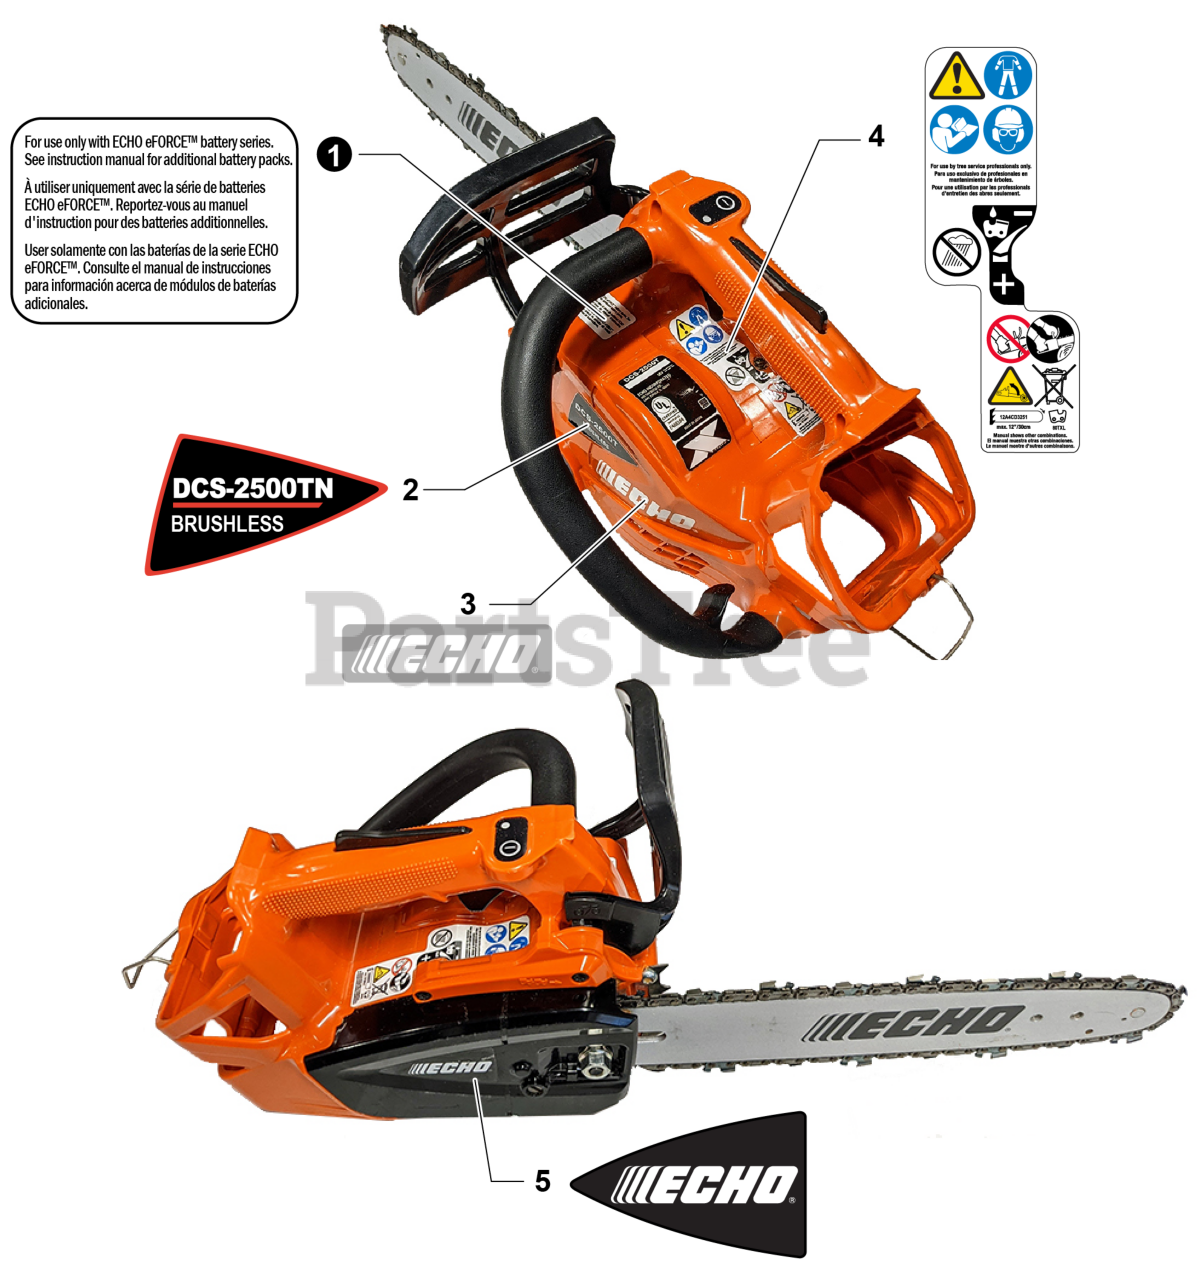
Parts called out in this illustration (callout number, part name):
1	LABEL - CAUTION - BATTERY
2	LABEL - MODEL - DCS-2500TN
3	LABEL - ECHO
4	LABEL - CAUTION - UL
5	LABEL - ECHO
